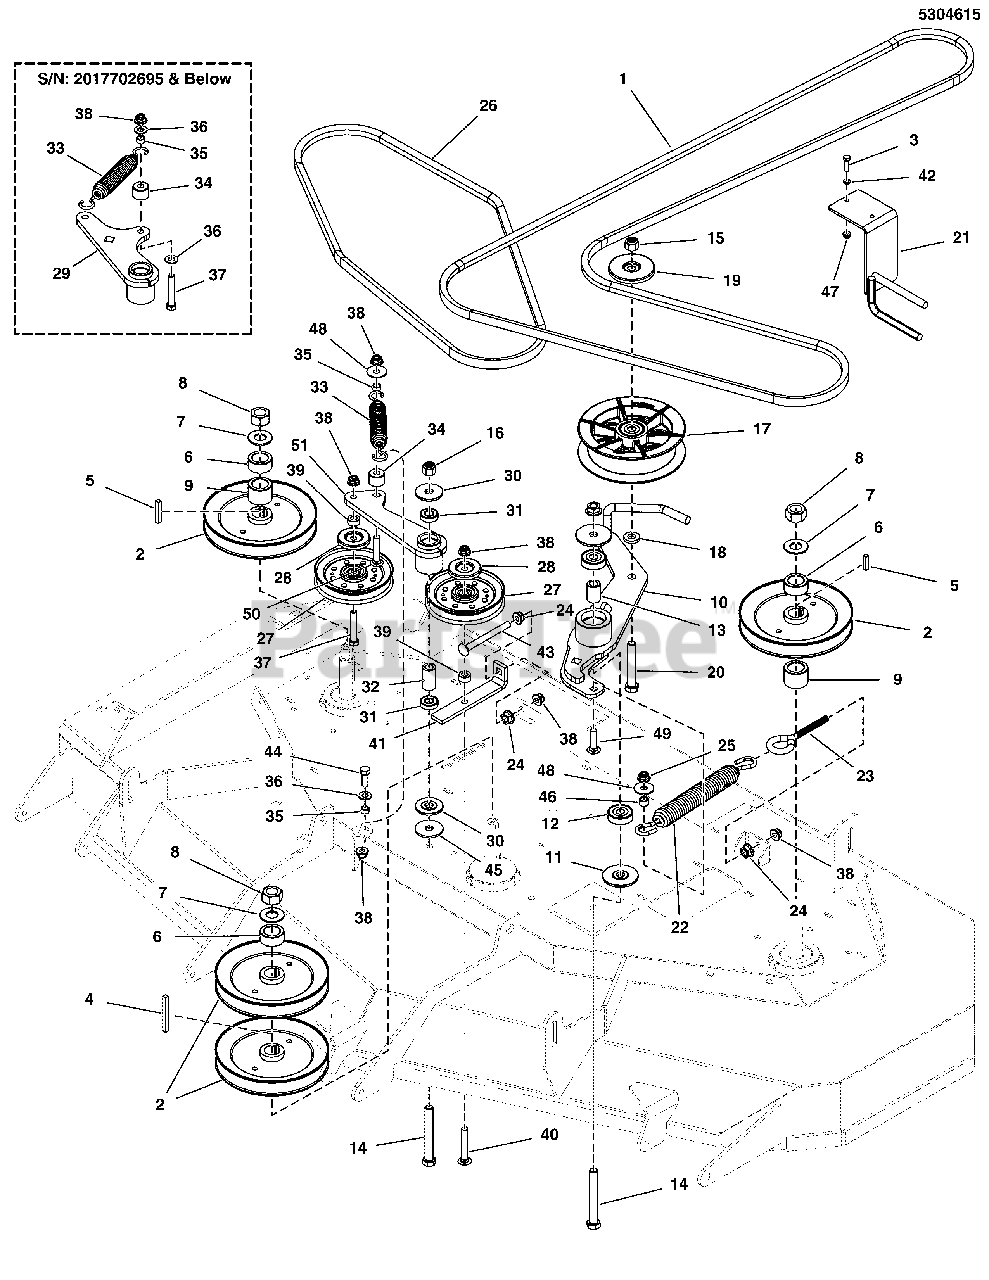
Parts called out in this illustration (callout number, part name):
1	BELT, 5V/SPB, 138.50 EL, LG ARAMID, WRPD
2	PULLEY, SPNDL, 7.032"OB X .985"ID
3	BOLT, 1/4-20 X 1", GD
4	KEY, 1/4" SQ. X 2 1/4
5	KEY, 1/4 Square x 1
6	SPACER, 1.00 X 1.50 X .70, BZ
7	WASHER, 3/4" Belleville (Included with Complete Spindle Assembly)
8	NUT, 3/4-16 Hex (Included with Complete Spindle Assembly)
9	SPACER, 1.00 X 1.50 X 1.14, BZ
10	WELD, IDLER ARM, DECK DRIVE - BLK
11	SPACER, IDLER ARM, 1/2 X 2.25
12	BEARING, 6203-1/2", SEALED
13	SPACER, .51 X .75 X 1.22, PM, CZ
14	BOLT, 1/2-13 X 4 GD5 YZ
15	NUT, 1/2-13 HEX NYLON LOCK
16	NUT, Hex Flange, 1/2-13
17	PULLEY, IDLER, 5.50, CI, DBL BEARING
18	SPACER, .52 X 1.00 X .22, PM, CZ
19	SHIELD, PULLEY, 1/2"ID X 2-7/8"OD, CZ
20	BOLT, 1/2-13 X 3-1/4, HEX HD, GD5, YZ
21	WELD, CLUTCH, BELT GUIDE - BLK
22	SPRING, EXT1.22"ODX10.5"FLX.192"WIRE BLK
23	EYEBOLT, 3/8-16 X 5, 2.88 THRD (5021812)
24	NUT, Hex, Serrated Flange, 3/8-16 (S/N 616 & up)
25	NUT, 3/8-16, Hex Flange Nylock
26	BELT, B-SEC, 64.00 EL, ARAMID, WRPD
27	PULLEY-IDLER-V, 4.85OB, .38ID
28	SHIELD, PULLEY, 3/8"ID X 2"OD, CZ
30	SPACER, IDLER ARM, 1/2, PM
31	BEARING, 1.125" OD, .5" ID, .3125" Wide, Ball
32	SPACER, .52 X .84 X 1.53, PM
33	SPRING, Extension (48" Model - SN: 426 & up)(52: Model - SN: 351 & up)
34	SPACER, .39 X 1.00 X .75, CZ
35	SPACER, .38 X .50 X .27, CZ
36	WASHER, 3/8 (.406 X .816 X .65), Flat, Zinc/Clear
37	CAPSCREW, Hex Head, 3/8-16 X 1-3/4
38	NUT, 3/8-16, Hex Flange Nylock
39	SPACER, .39 X 1.00 X .38
40	BOLT, 3/8-16 X 2-1/2, CARRIAGE, GD5, CZ
41	PLATE, IDLER PULLER - BLK
42	WASHER, 1/4, Flat, GR5 Zinc/Clear
43	BOLT, 3/8-16 X 4-1/2, CARRIAGE, GD5, CZ
44	CAPSCREW, Hex Head, 3/8-16 x 1
45	WASHER, .52 X 1.75 X .14, CZ
46	SPACER, .39 X .63 X .375, DOM
47	NUT, 1/4-20, GR5 Flanged Nylock, Zinc/Clear
48	WASHER, Fender, 3/8
49	BOLT, Carriage, 3/8-16 X 1 1/2, GR5
50	BOLT, 3/8-16 X 2, CARRIAGE, GD5, CZ
51	WELD, IDLER ARM, 2 BELT DRIVE - BLK
